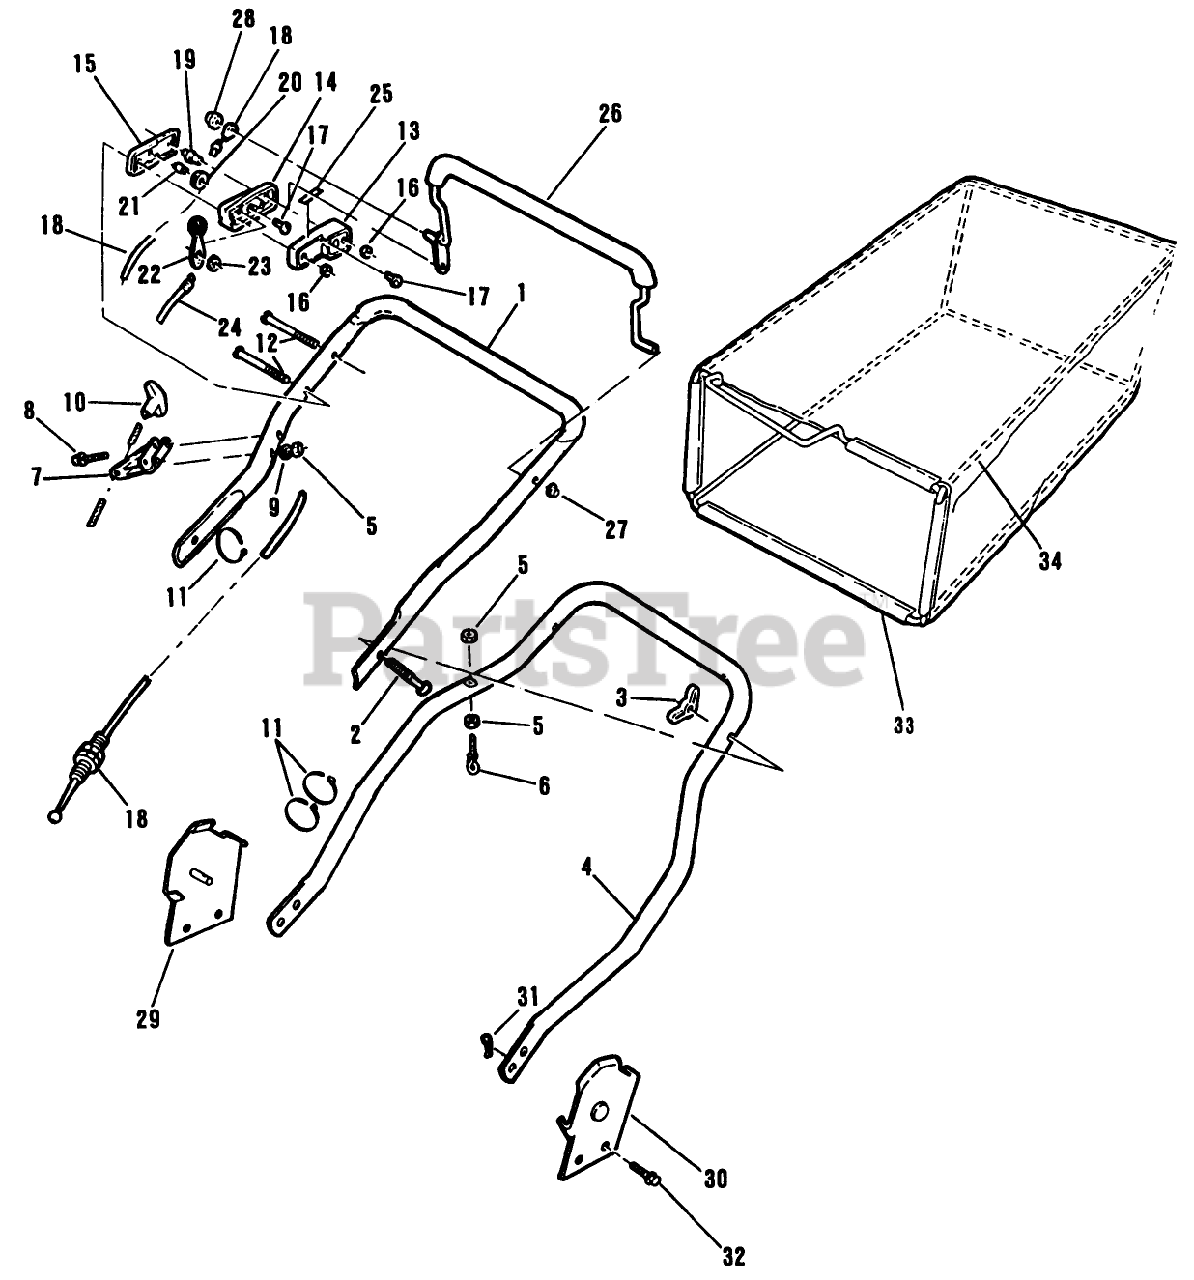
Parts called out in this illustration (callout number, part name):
1	HANDLE-TOP *G
2	BOLT QUALITY
3	NUT-WING
5	LOCKNUT E
6	EYE BOLT WAS MFG
9	WASHER
10	HANDLE START UM&D
12	SCREW
16	NUT C/LOCK E
17	SCREW
18	CONTROL CABLE WES
19	COLUMN
20	PULLEY PL
21	PIN SKF
22	LEVER&KNOB AY WES
23	WASHER-SPRING
24	CABLE THROT WES
28	NUT ACORN
31	HAIR PIN
